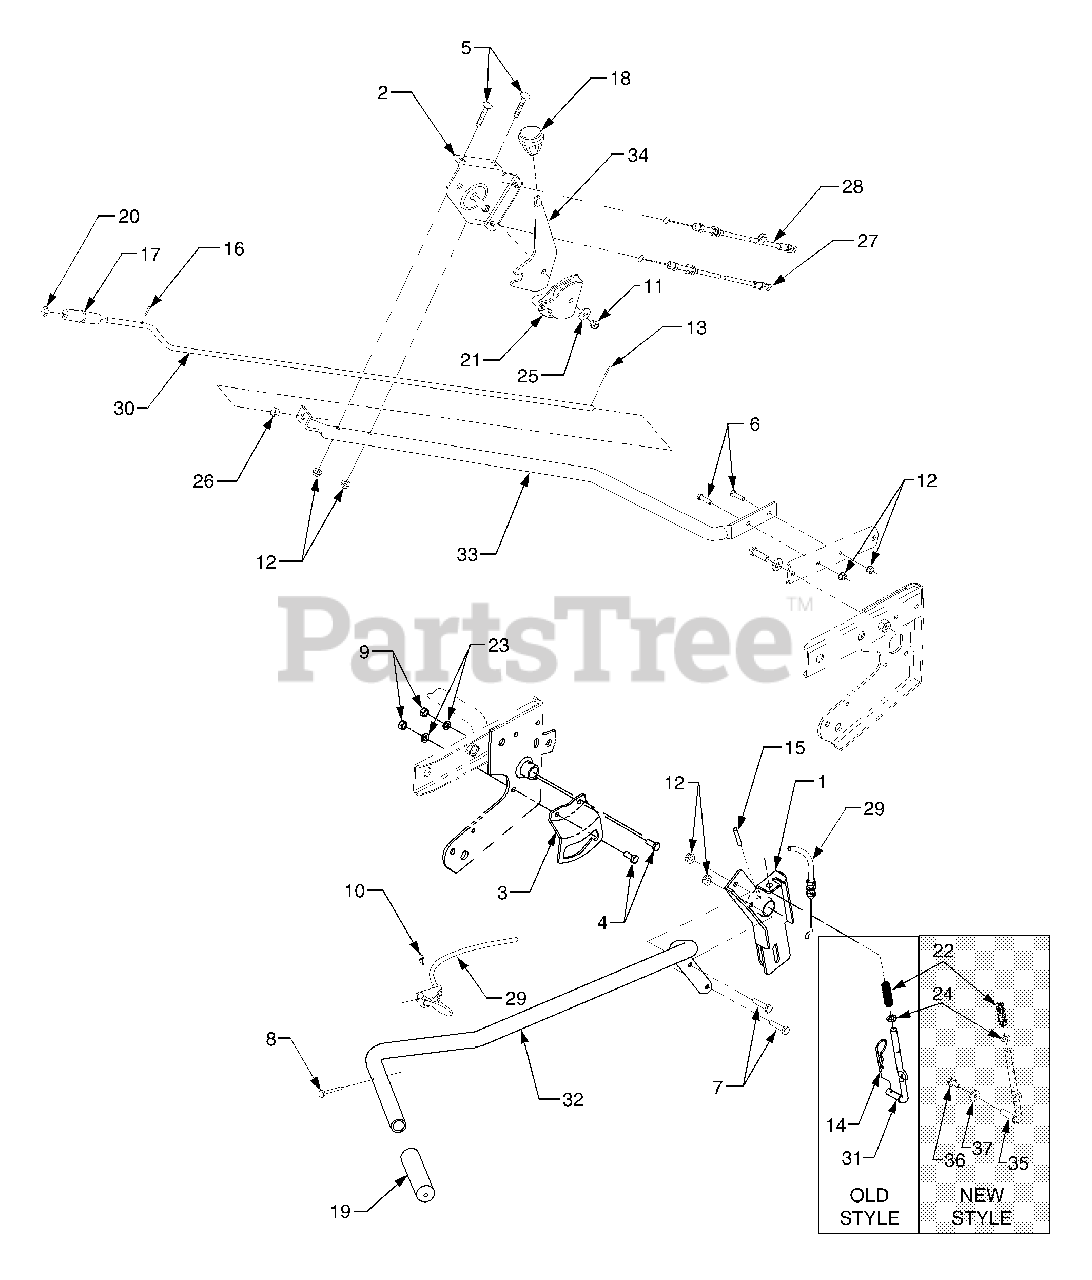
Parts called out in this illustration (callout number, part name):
1	Bracket, Lift
2	Bracket, Chute Tilt
3	Bracket, Lift Handle Latch
4	Screw, Hex Cap 5/16-24 x .75 GR5
5	Bolt, Carriage 5/16-18 x 1.5 GR2
6	Screw, Hex Cap 5/16-18 x 1.25 GR5
7	Screw, Hex Cap 5/16-18 x 1.5 GR5
8	Screw, Oval Hd. Cntsk. Mach. 10-24 x 1.375
9	Nut, Hex, 5/16-24
10	Nut, Flat Weld, 10-24
11	Nut, Hex Insert Lock, 5/16-18
12	Nut, Hex Flange Lock, 5/16-18
13	Pin, Cotter, 3/32 x .75
14	Pin, Internal Cotter
15	Pin, Spirol, 1/4 x 1-1/2
16	Pin, Roll, 1/8 x .63
17	Knob, Chute Crank
18	Knob, Tilt Handle
19	Grip, Lift Handle
20	Cap, Push
21	Guide, Cable
22	Spring, Compression
23	Washer, Lock, 5/16
24	Washer, Flat, .385 x .620 x .063
25	Washer, Bell, .340 x .872 x .06
26	Bushing, Plastic
27	Cable, Chute Control
28	Cable, Chute Control w/Clip
29	Cable/Trigger Assembly, Lift Latch
30	Rod, Chute Crank
31	Rod, Lift Latch
32	Handle, Lift
33	Tube, Chute Crank Support
34	Handle, Chute Tilt
35	Rod, Lift Latch
36	Screw, Hex Wash, Hd Tapp #10-16 x .375
37	Washer, Flat, .194 x .62 x .063
